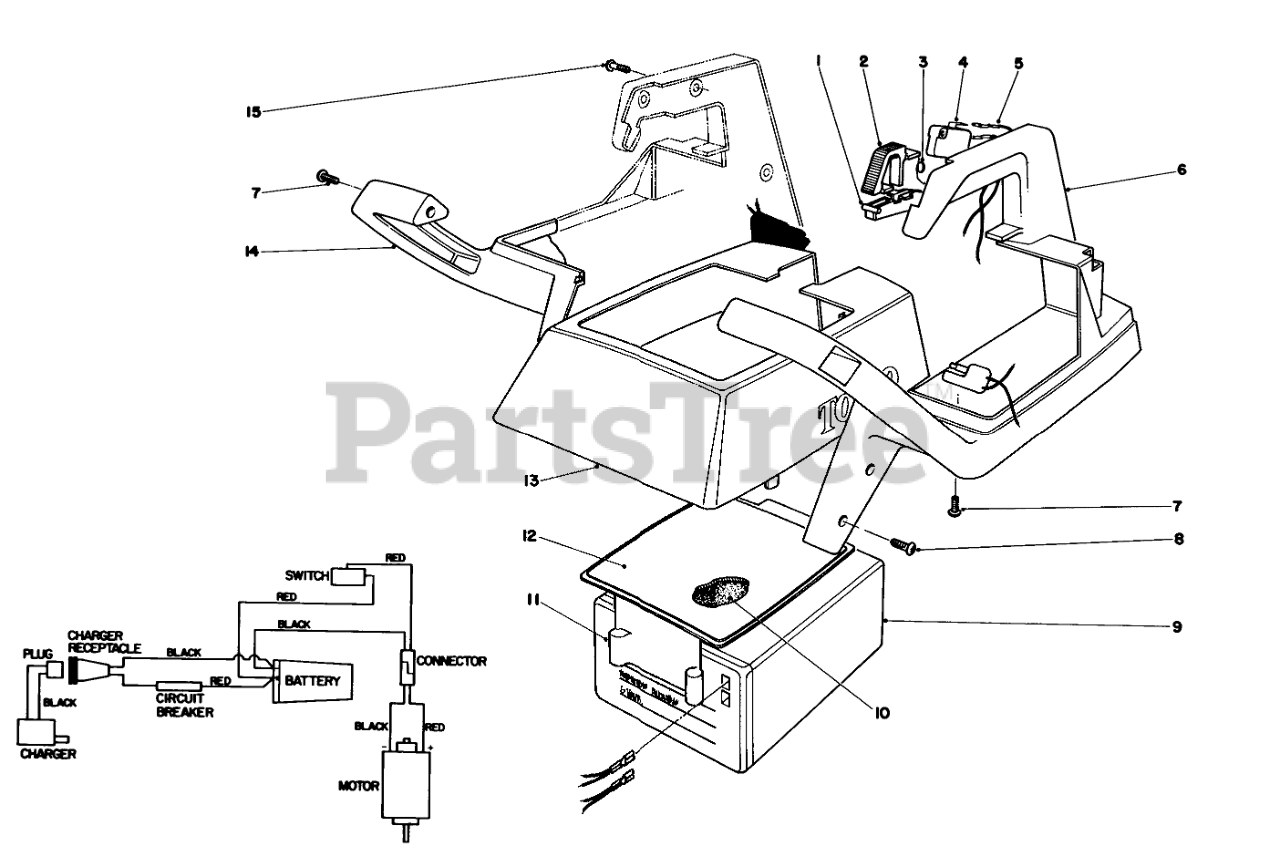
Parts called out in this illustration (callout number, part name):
1	TRIGGER
2	TRIGGER LOCK
3	SPRING
4	Switch
5	Wiring Harness
6	LH BATTERY CASE/HNDL
8	10-16 X .31 SCREW
9	BATTERY
10	FOAM PAD
11	CONTROL PANEL, CL-710
12	DECAL CL 710 PANEL
13	Cover
14	RH BATTERY CASE/HNDL
